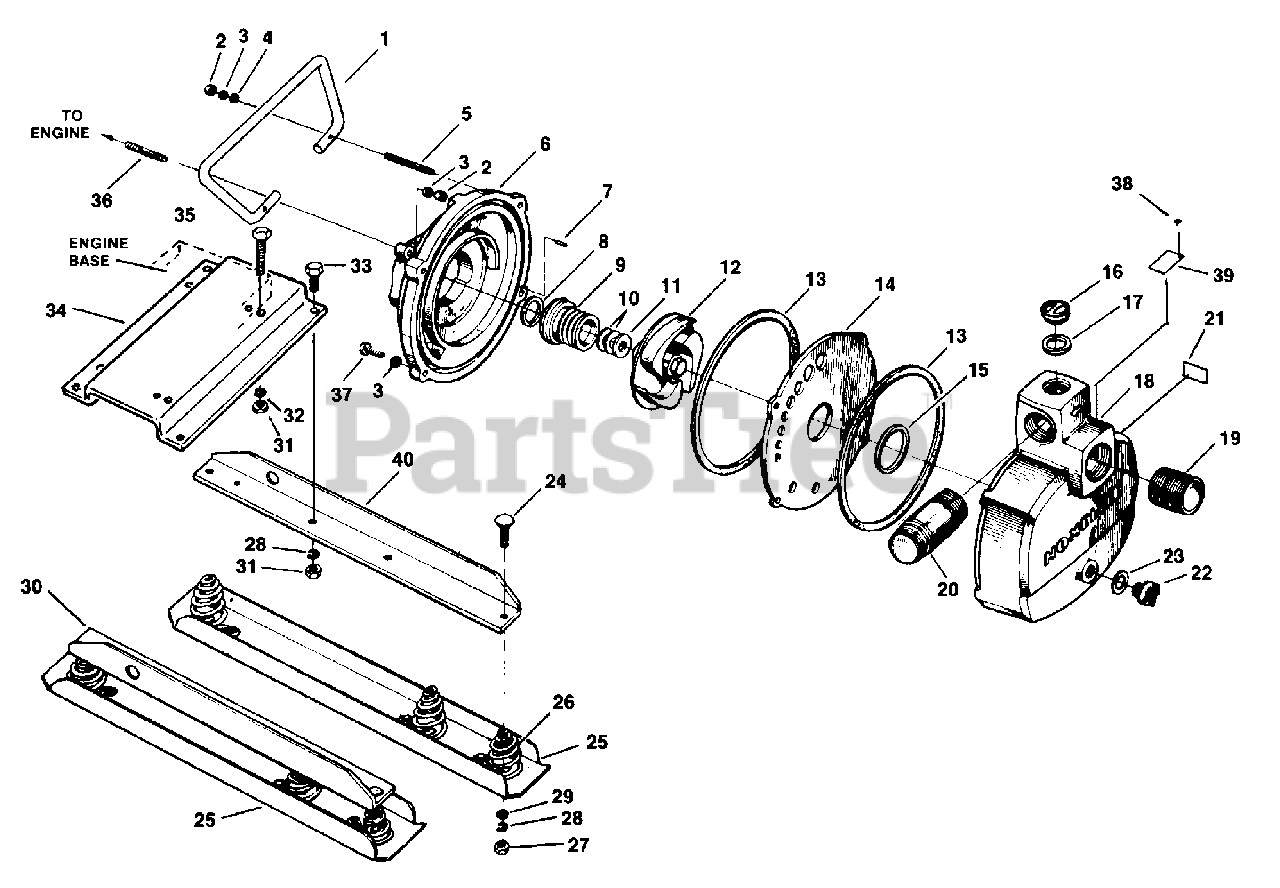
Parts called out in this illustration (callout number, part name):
2	NUT- 3/8-16
3	WASHER- Lock, 3/8"
4	WASHER- Flat, 3/8"
6	HOUSING- Impeller
7	PIN- Coiled spring
8	SLINGER
9	SEAL ASSEMBLY
10	SHIM- Seal (.010")
12	IMPELLER
13	GASKET- Large
14	PLATE- Wear
15	GASKET- Small
16	PLUG- Filler
18	HOUSING- End
19	NIPPLE- Suction
20	FITTING- Pipe (discharge)
21	DECAL- Fill pump
22	PLUG- Drain
24	SCREW- Hex hd, 5/16-18 x 1"
25	SKID ASSEMBLY
27	NUT- Hex, 5/16-18
28	WASHER- Lock, 5/16"
29	WASHER- Flat, 5/16"
30	ANGLE- Base (right)
31	NUT- Hex, 5/16-18
32	WASHER- Lock 5/16"
33	SCREW- Hex, 5/16-18 x 3/4"
34	BRACKET- Engine mounting
35	SCREW- Hex, 5/16-18 x 13/4"
37	BOLT- 3/8-16 x 1 1/2"
38	TACK- Metal
39	PLATE- Warning
40	ANGLE- Base (Left)
